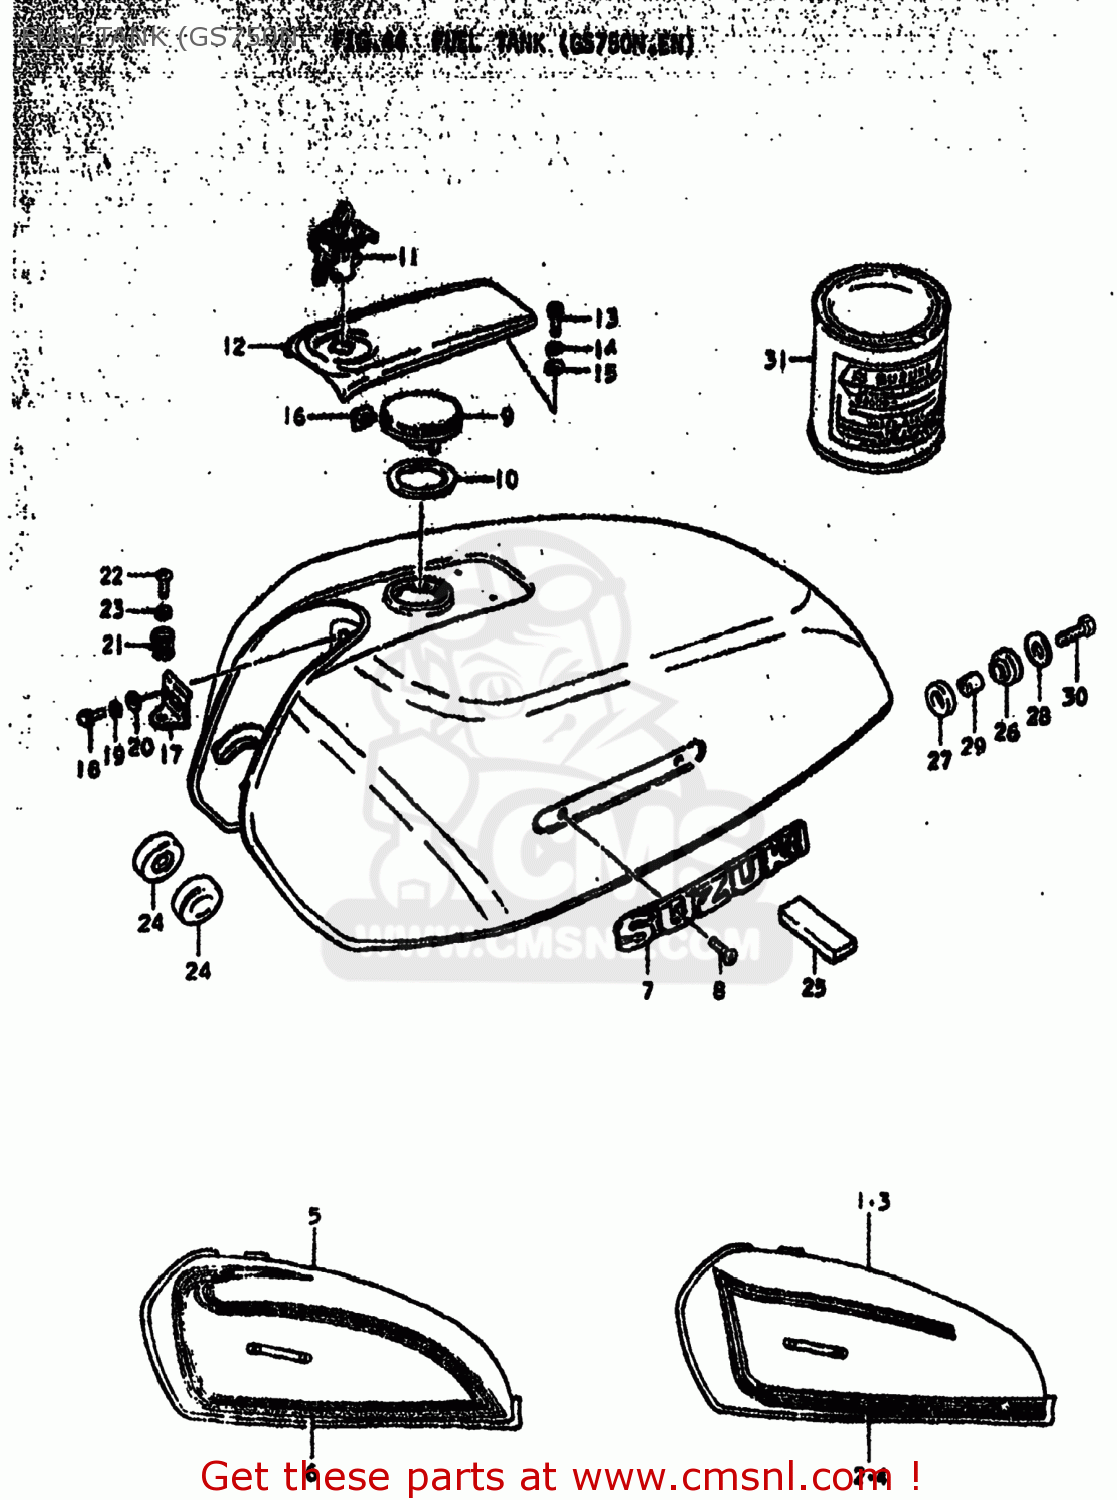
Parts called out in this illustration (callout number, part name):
1	TANK ASSEMBLY,FUEL
3	TANK ASSEMBLY,FUEL
5	TANK ASSEMBLY,FUEL
6	TAPE SET
7	EMBLEM,FUEL TANK
8	SCREW 3X6
9	CAP,FUEL TANK
10	GASKET (NAS)
11	LOCK,FUEL TANK FR COVER
12	COVER,FUEL TANK FR
13	BOLT
14	LOCK WASHER
15	WASHER
16	CUSHION,FUEL TANK FR COVER
17	HOLDER,FUEL TANK FRONT COVER
18	BOLT
19	LOCK WASHER
20	WASHER
21	SPRING
22	SCREW
23	LOCK WASHER
24	CUSHION
25	CUSHION
26	CUSHION
27	CUSHION
28	WASHER (8.5X29X1.6)
29	SPACER (8.2X12X17)
30	BOLT (8X30)
31	PAINT,BLACK
